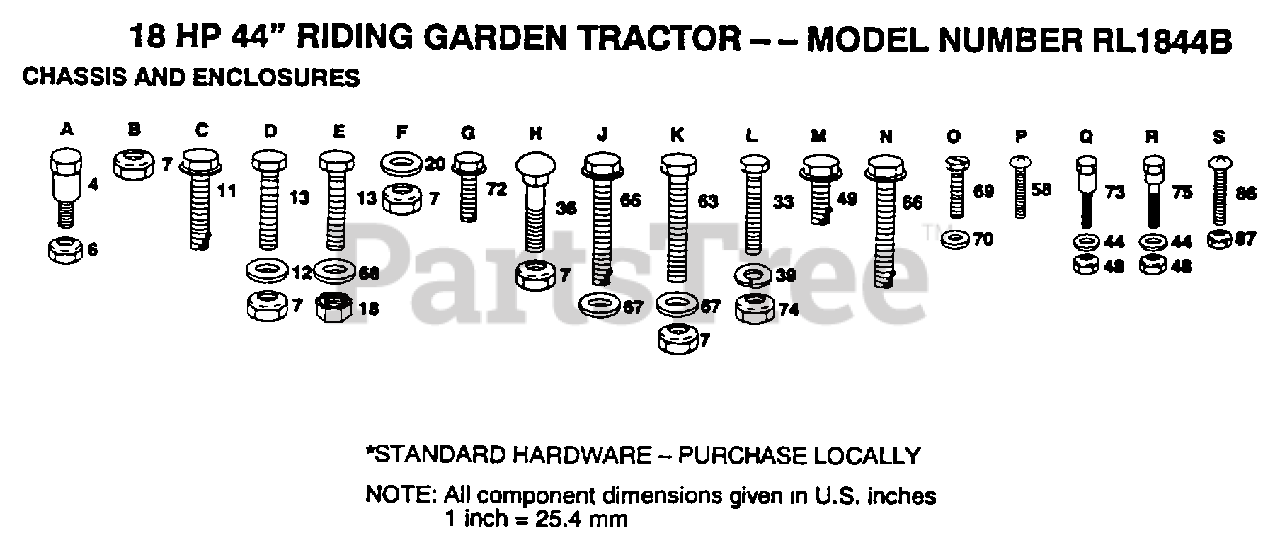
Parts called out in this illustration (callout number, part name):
11	SCREW
12	WASHER
18	NUT
20	WASHER
33	BOLT LT
36	BOLT
39	LOCKWASHER
49	SCREW LT
63	BOLT
66	SCREW GTV
67	WASHER HYT
68	WASHER
69	SCREW
73	BOLT T
75	"BOLT,SHOULDER"
87	"NUT,KEPS"
